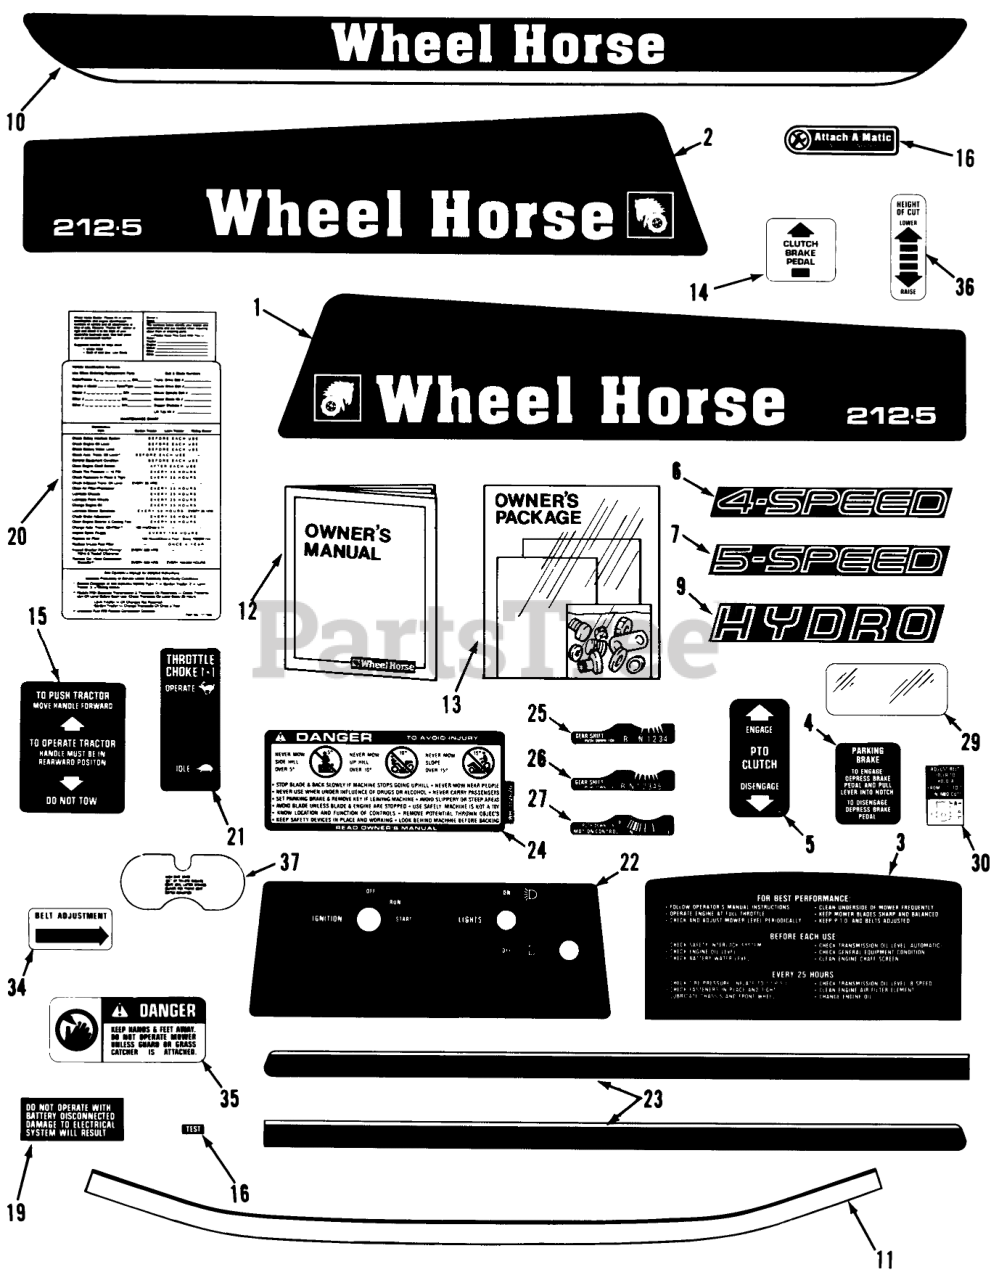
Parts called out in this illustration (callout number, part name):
2	DECAL-HOOD 212-HS
5	DECAL-PTO
11	DECAL FRONT HOOD
12	Owner-s Manual-208, 211-s 212-5
12	Owner-s Manual-212-H Only
14	DECAL CLUTCH & BRAKE
20	MAINTENANCE-DECAL
23	DECAL-HOOD STRIPE LH
24	DECAL-DANGER
29	DECAL-OVERLAY
36	DECAL-HOC
